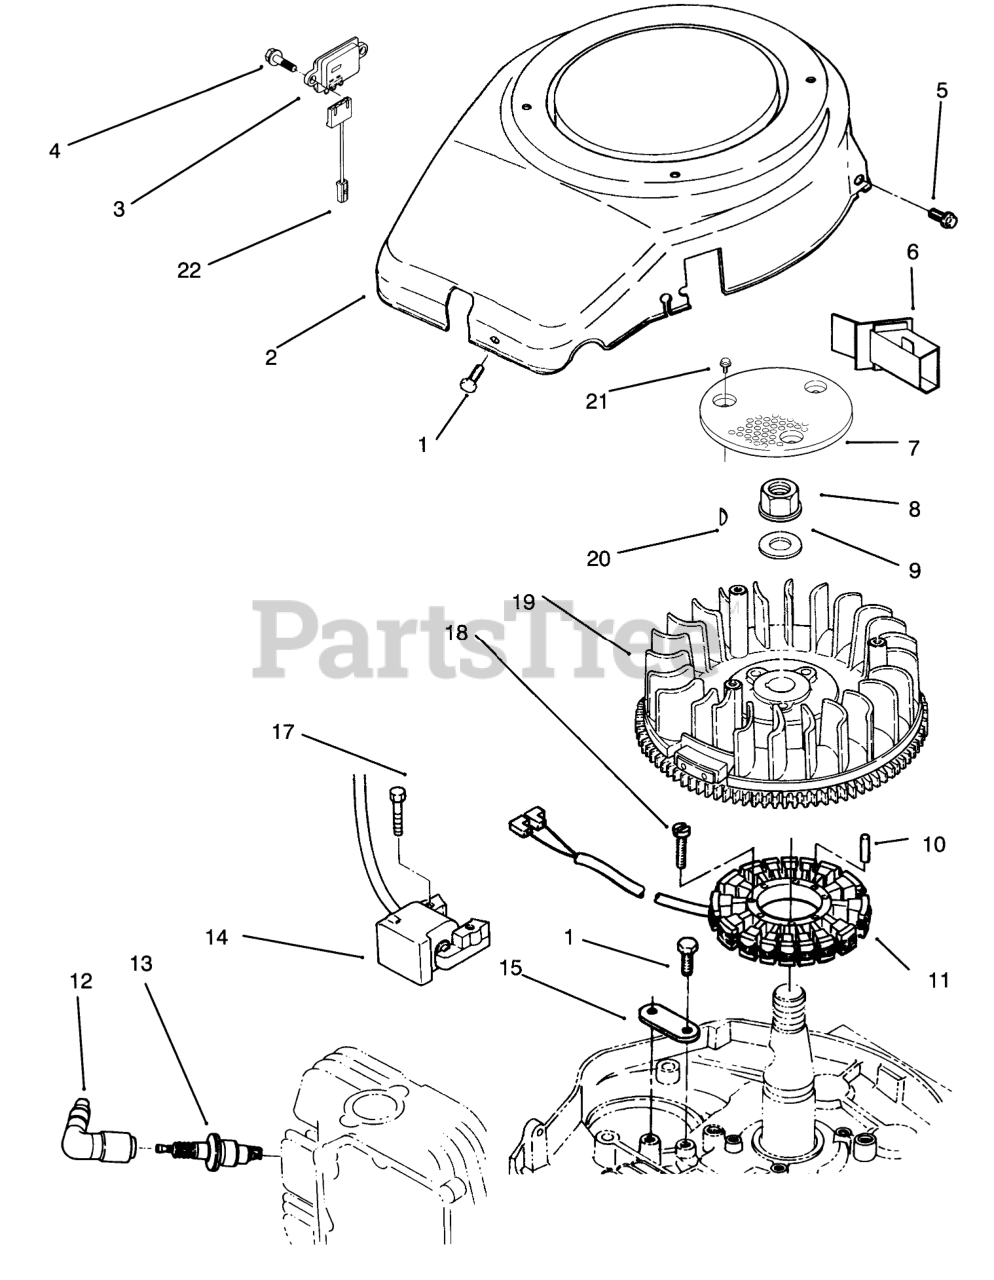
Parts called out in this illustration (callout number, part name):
1	HHSTB-M6 X 14MM
2	BLOWER HOUSING ASM
3	VOLTAGE REGULATOR
4	SCREW-HWH
5	FLANGE LOCK SCREW
6	AIR INLET TUBE
7	RH AIR CYLINDER HSG
8	NUT-FLANGE M18
9	FLAT WASHER
10	PIN-ALIGNMENT
11	ALTERNATOR STATOR
13	SPARK PLUG
14	IGNITION COIL
15	DECAL-SHIFT 5 SPEED
17	SCREW-HWH
18	SCREW
19	WHL-ASS'Y BLOWER
21	HHCS-M6 X 10MM
22	ENG WIRING HARNESS
